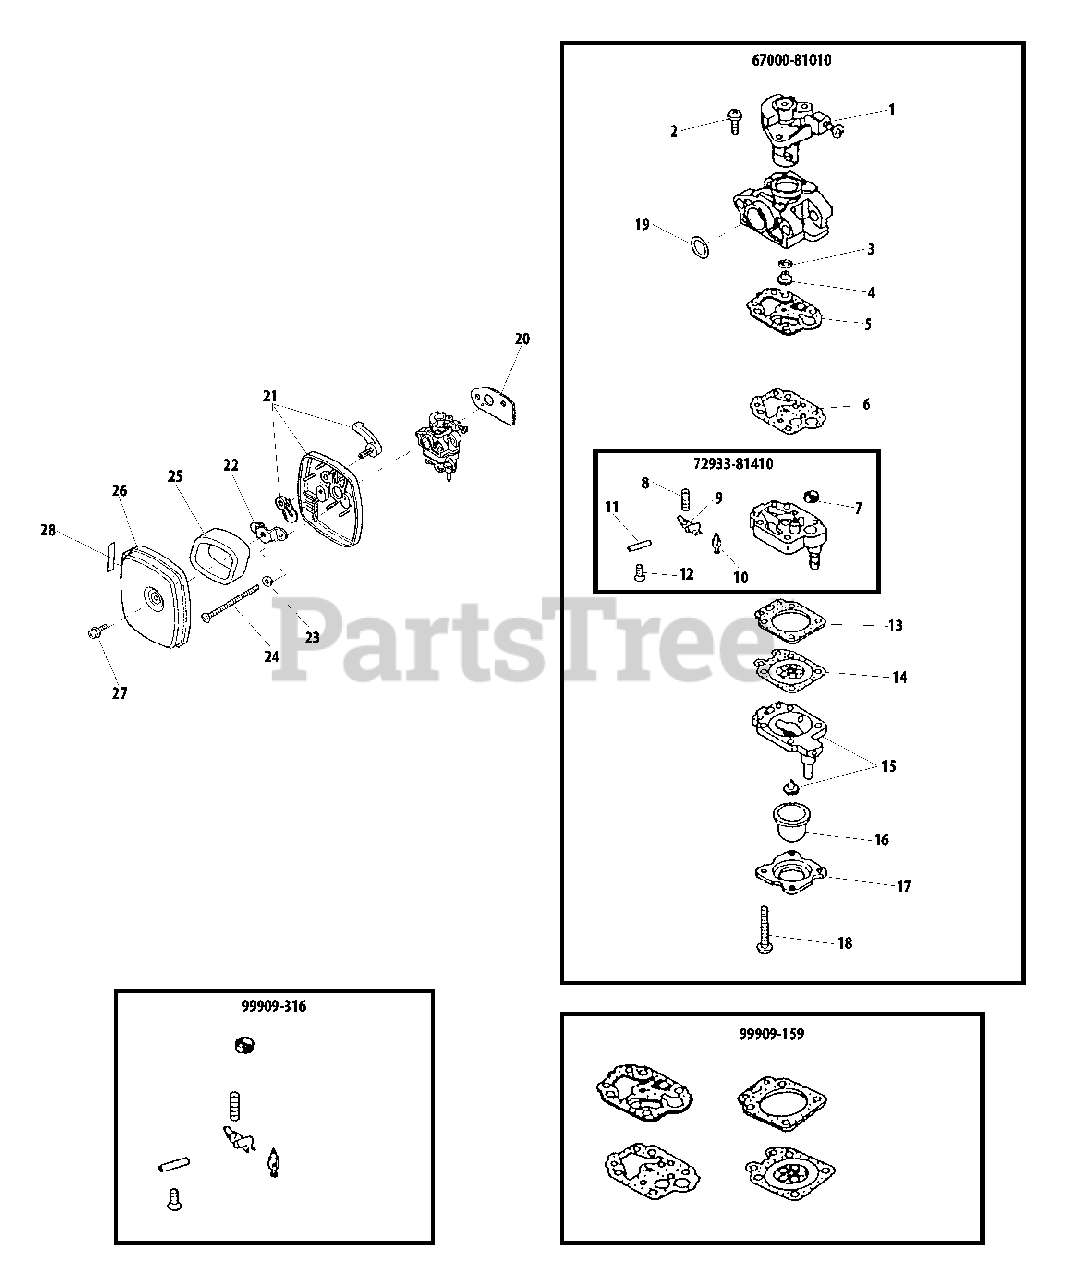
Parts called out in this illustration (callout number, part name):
1	THROTTLE VALVE ASSY
2	SCREW
3	O-RING
4	JET, MAIN - 35
5	GASKET, PUMP
6	DIAPHRAGM, PUMP
7	STRAINER
8	SPRING, METERING LEVER
9	LEVER, METERING
10	VALVE, INLET NEEDLE
11	PIN, METERING LEVER
12	SCREW, METERING LEVER PIN
13	GASKET, METERING
14	DIAPHRAGM, METERING
15	BASE, PURGE
16	BULB, PURGE
17	RETAINER, PURGE BULB
18	SCREW, PUMP COVER
19	O-RING - 15
20	GASKET, INTAKE
21	CASE, AIR FILTER
22	PLATE, PREVENT
23	WASHER - 5
24	SCREW - 5X60
25	FILTER, AIR
26	COVER, AIR FILTER
27	SCREW
28	LABEL - CHOKE
67000-81010	CARBURETOR
72933-81410	BASE, PURGE
99909-159	DIAPHRAGM/GASKET KIT
99909-316	REPAIR KIT
